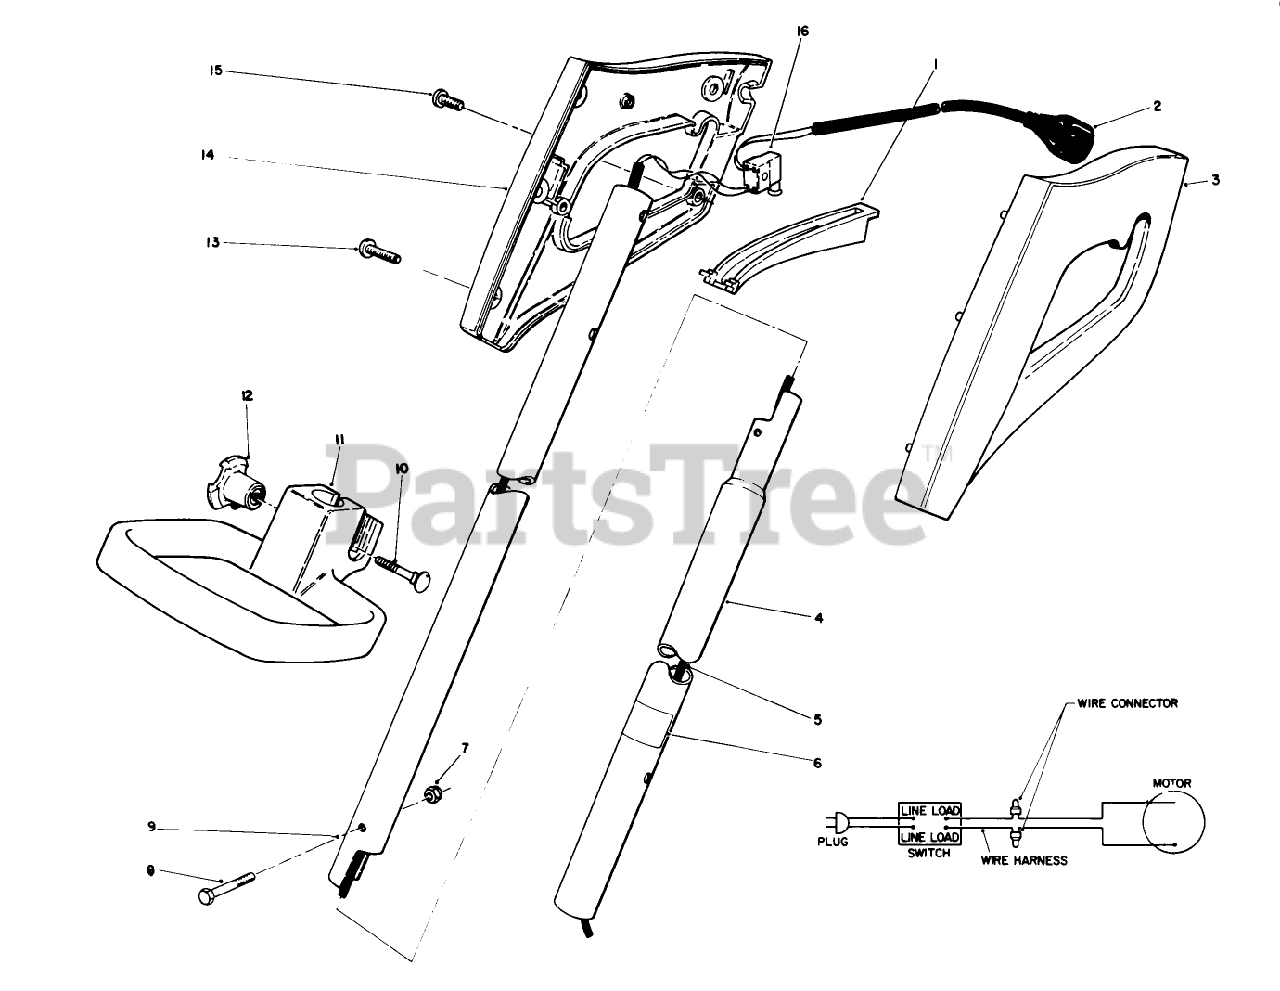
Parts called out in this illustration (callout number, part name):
1	Bar Switch
2	Cord-Power
3	Grip-L.H.
4	Tubing-Lower Extension
5	1010 WIRE HARNESS
6	REP. SERIAL PLT
7	NUT-LOCK, NI
8	HEX HD MACHINE SCREW
9	UPPER EXT TUBING
10	BOLT-CARR
11	Handle
12	Knob
13	Screw
14	Grip R.H.
15	SCREW-PPH
16	SWITCH
